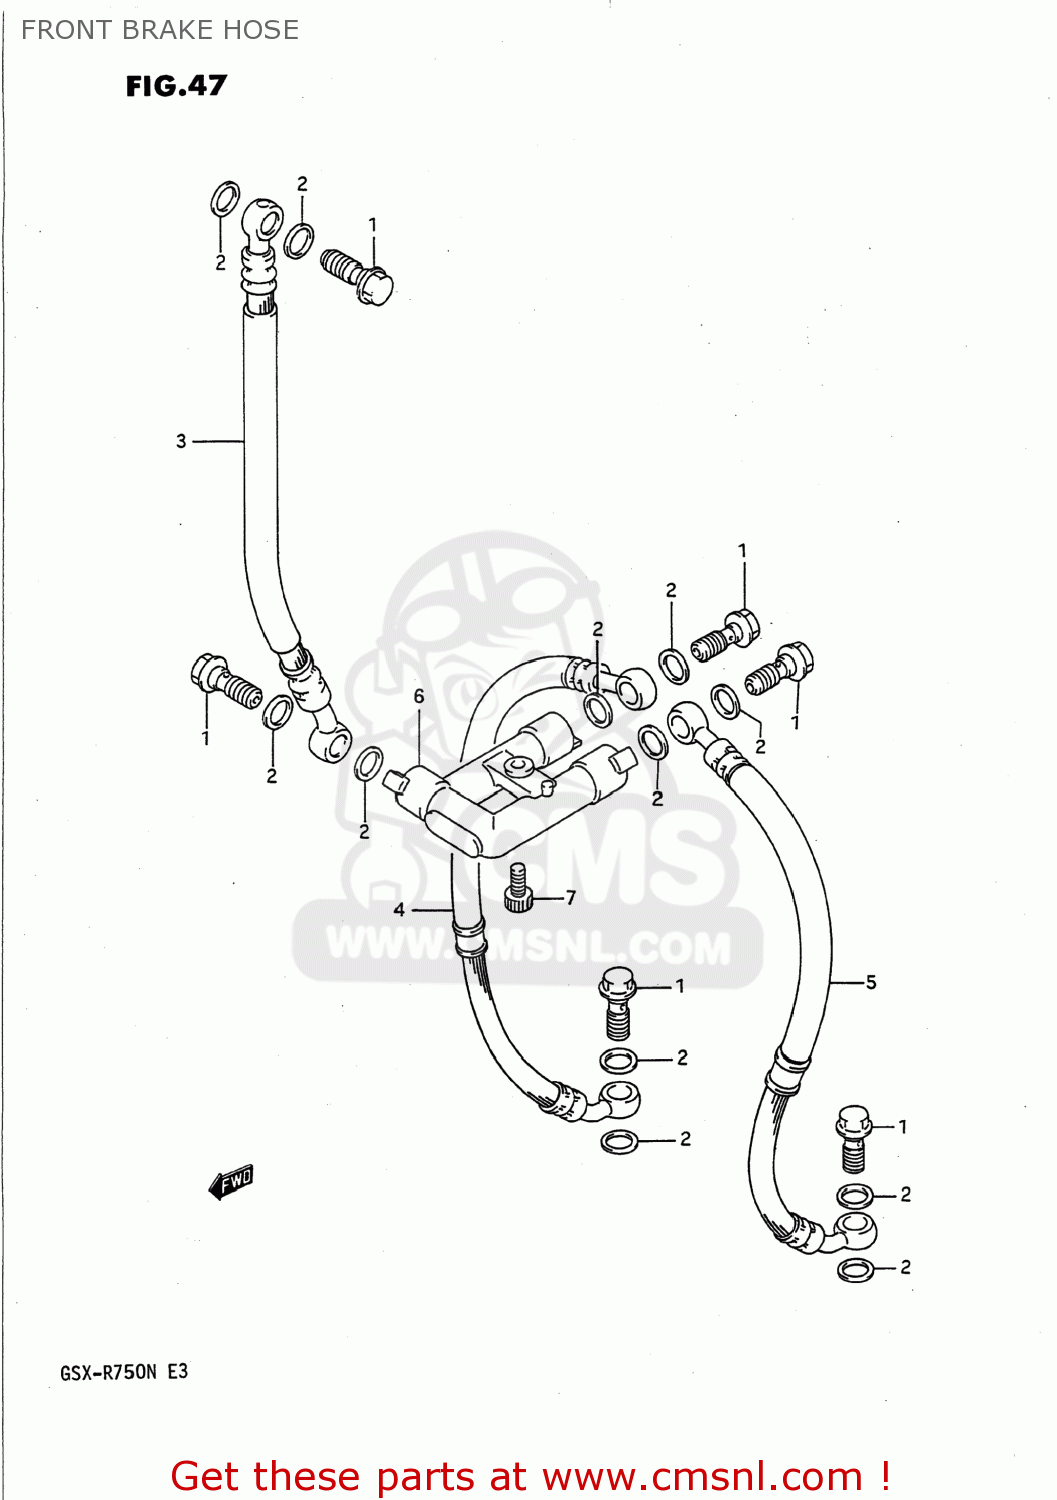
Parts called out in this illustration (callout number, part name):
1	BOLT UNION
2	WASHER(10X15X1.5)
3	HOSE COMP,FRONT BRAKE
4	HOSE COMP,FRONT BRAKE
5	HOSE,FR BRAKE NO.2,L
6	JOINT,BRAKE HOSE
7	BOLT
